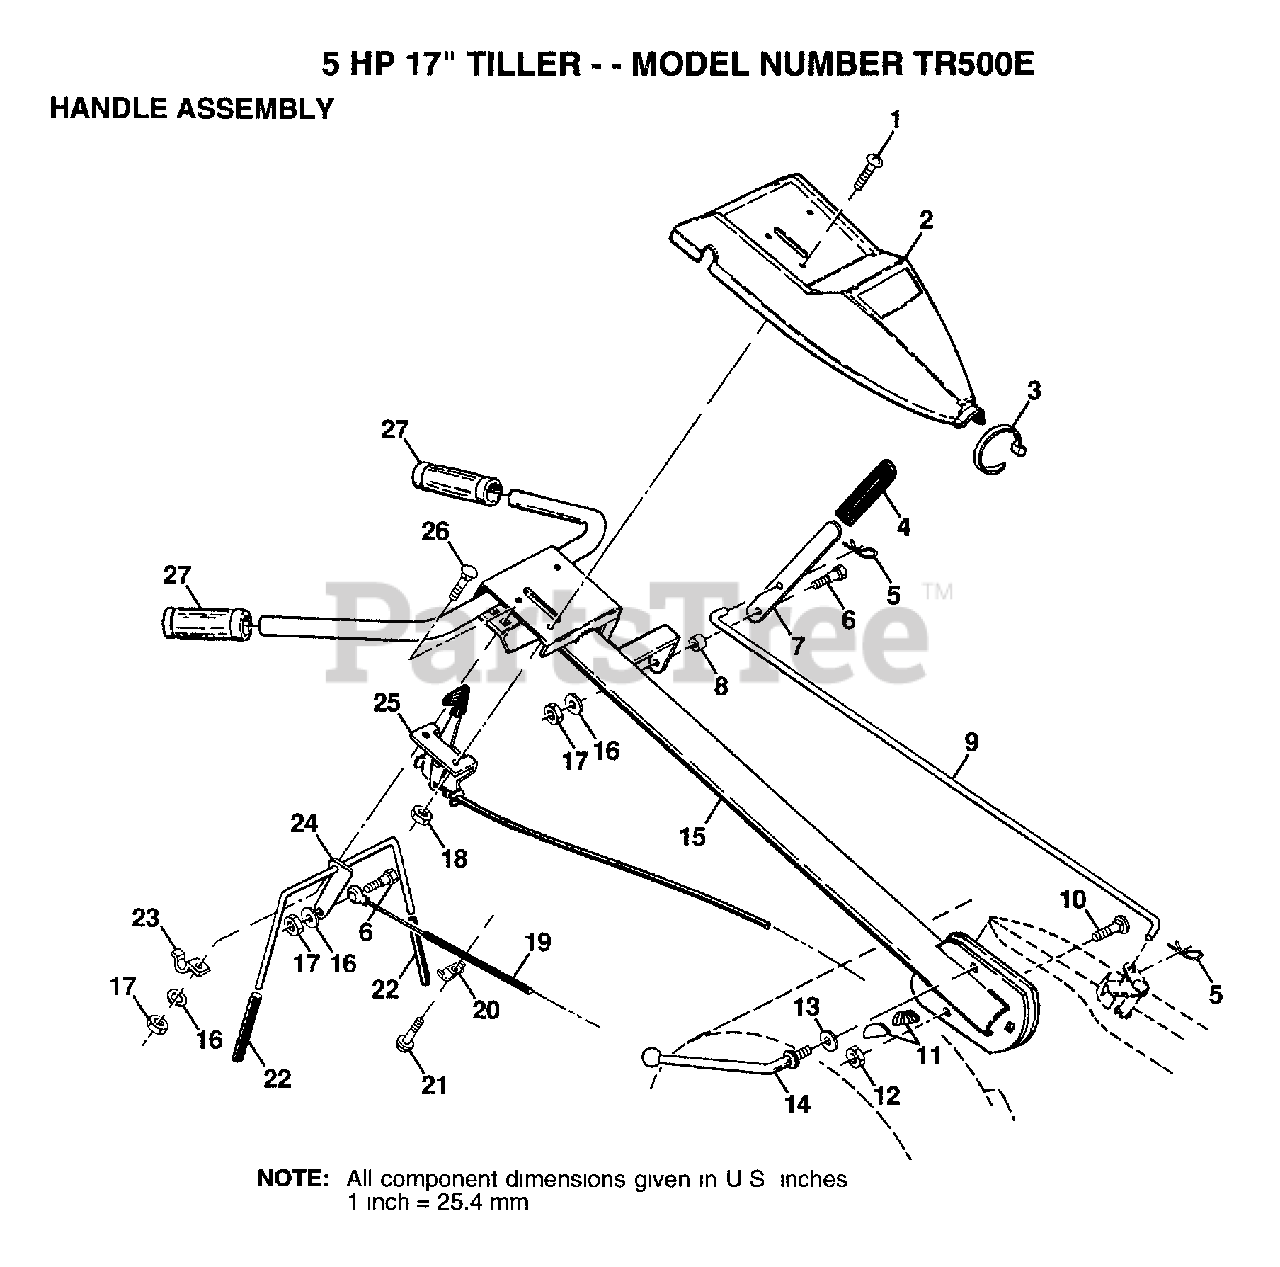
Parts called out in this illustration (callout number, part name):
1	SCREW
2	"PANEL,CONT TI"
3	TIE CABLE CRT
4	GRIP T
5	RETAINER M
6	SHOULDER BOLT ST
7	SHIFT HANDLE CRT
8	GROMMET CRT
9	SHIFT ROD CRT
10	BOLT D
11	LOCK CRT
12	LOCKNUT
13	WASHER CRT
14	LEVER LOCK CRT
15	HANDLE.ASM
16	LOCKWASHER
19	CABLE.CLUTCH.CRT
20	CONDIUT CLIP T
22	GRIP BAR CRT
24	"ASSY CONTROL, BAR"
25	"CONT,THROTTLE"
26	BOLT
27	GRIP NUB SNGL HDL
